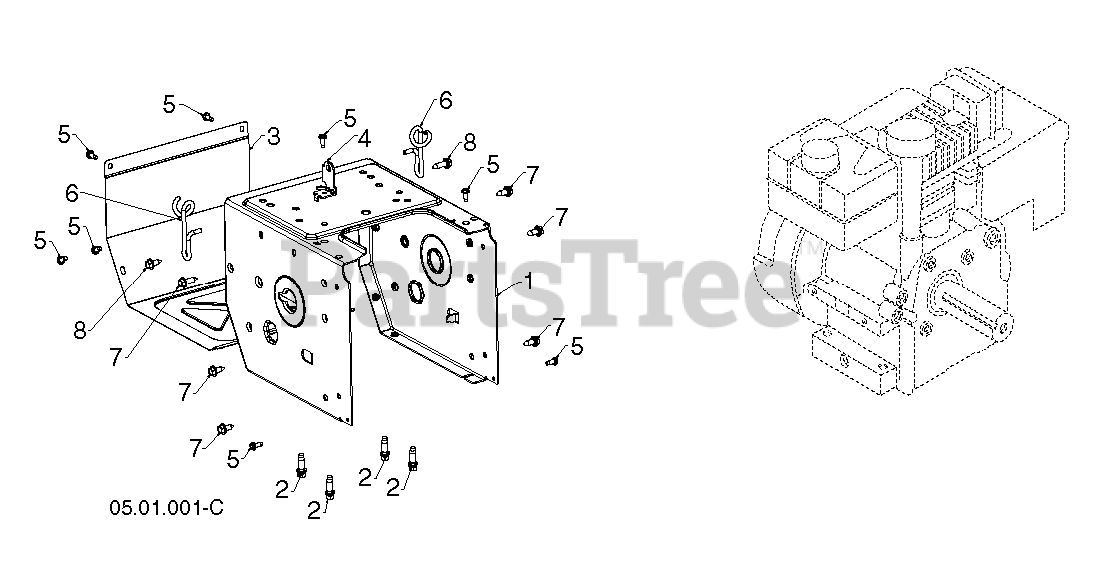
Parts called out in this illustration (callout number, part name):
1	FRAME.GEAR.CASE.ORANGE
2	BOLT 3/8-16X1-1/8
3	COVER COVER.FRAME MS668 ORANGE
4	BRACKET.SHIFTER.SNOW.BLACK
5	SCREW 14-20 X 5/8
6	RP.SUPPORT CABLES WIREFORM
7	BOLT.HEX.HD.WASHER.5/16-18X.75
8	SCREW HEX_SERR_HD_5_16-18X1.0
